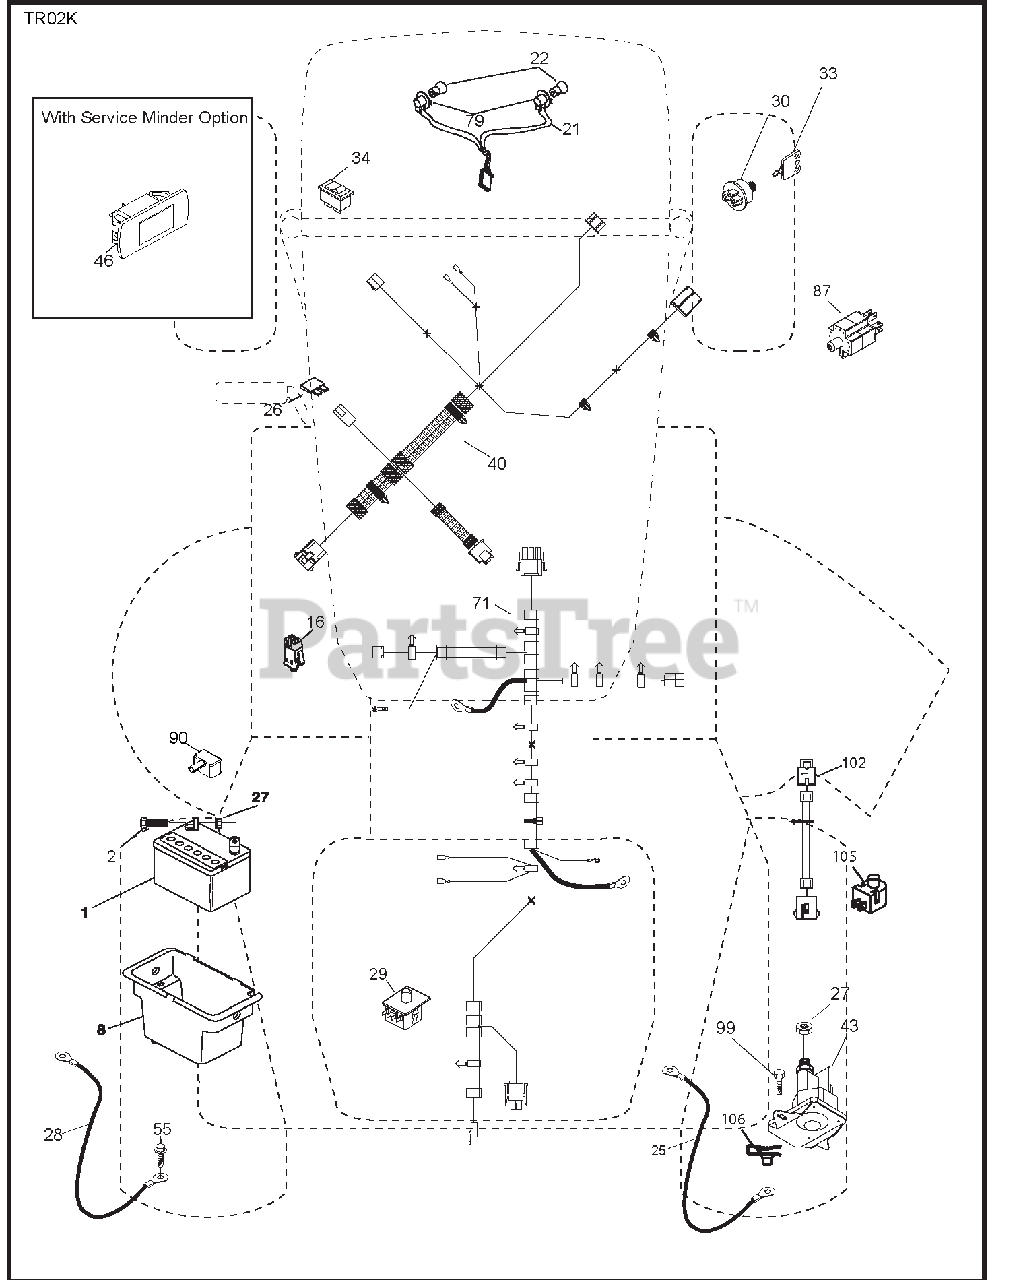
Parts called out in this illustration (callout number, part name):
1	BATTERY.12.VOLT.28.AMP.WET
2	BOLT.HEX.HD.1/4-20UNC X 3/4
8	BOX.BATTERY.MOUNT.FRONT.LT
16	SWITCH.INTERLOCK.NONO.GRAY
21	HARNESS ASM.LIGHT.22"(4152J)
22	BULB.LIGHT.#1156
24	CABLE.BTRY.PSWRE.DSH SOL.8"TEX
25	CABLE.STARTER
26	FUSE.20 AMP.
27	Nut, Keps Hex 1/4-20 unc
28	CABLE.BLACK.22"REAR BATT.TEX
29	SWITCH.SEAT.DELTA.OPC.9LB.
30	SWITCH.IGN.DLTA.P-IN.ROS
33	KEY/CHAIN.BLISTER PACK.GEN.USA
34	SWITCH.LIGHT/RESET.B/B/RED.
40	HARNESS IGN ELEC RELAY
43	SOLENOID.W/BRASS PLUNGER.2005
46	HOUR METER
50	SWITCH.PTO.8 TERMINAL.BLACK
55	SCREW.5/16-18X3/4.SMGML.TAP/R
71	HARNESS.IGN.CHASSIS.TEX
79	SOCKET ASM.BULB.TWISTLOCK
90	COVER TERMINAL BATTERY FR. TEX
91	STRAP.BATTERY.MOUNT.FRONT
100	WASHER.9/32 X 7/8 X 16GA.
102	HARNESS.PIGTAIL.K46.TEX.ROS
105	SWITCH.REVERSE.TT.PEDAL CONTRO
